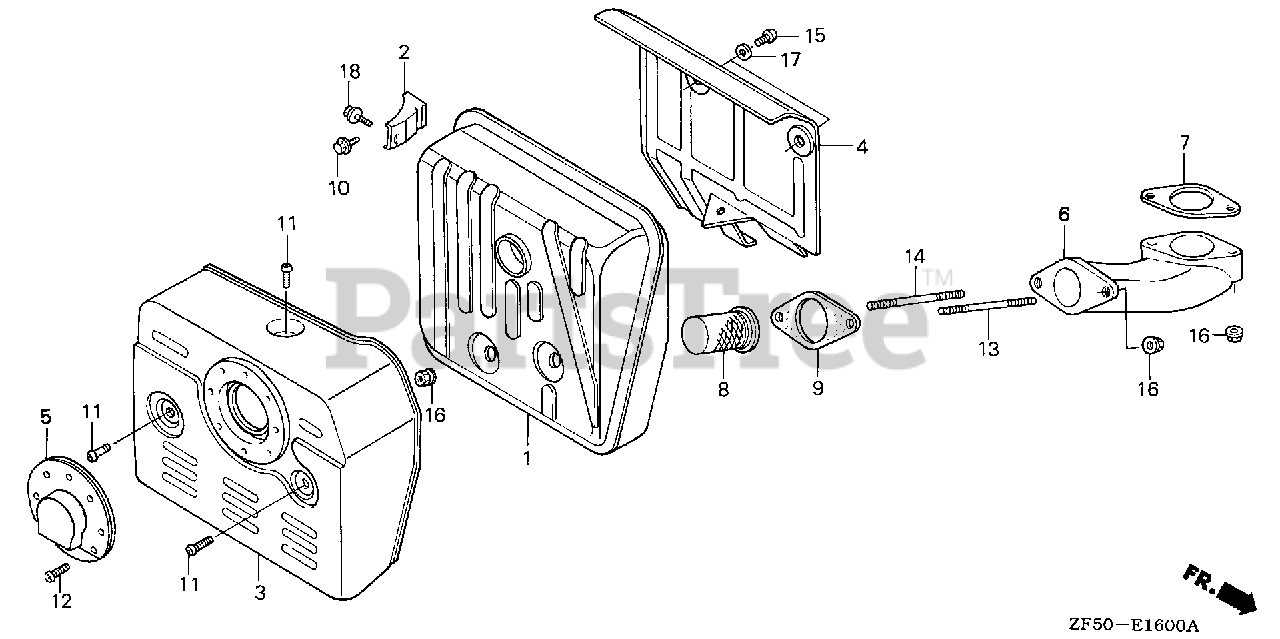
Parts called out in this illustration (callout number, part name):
2	STAY, MUFFLER
3	PROTECTOR, MUFFLER
4	SEPARATOR, MUFFLER
5	CAP, MUFFLER
7	GASKET, EX. PIPE
9	GASKET, EX. PIPE Use up to Engine SN 2015631.
9	GASKET, EX. PIPE
10	BOLT, FLANGE (8X16)
11	SCREW, TAPPING (5X8)
12	SCREW, TAPPING (4X6)
13	BOLT, STUD (8X60)
14	BOLT, STUD (8X70)
15	SCREW, PAN (6X6)
16	NUT, FLANGE (8MM)
17	WASHER, PLAIN (6MM)
18	BOLT, FLANGE (8X14)
